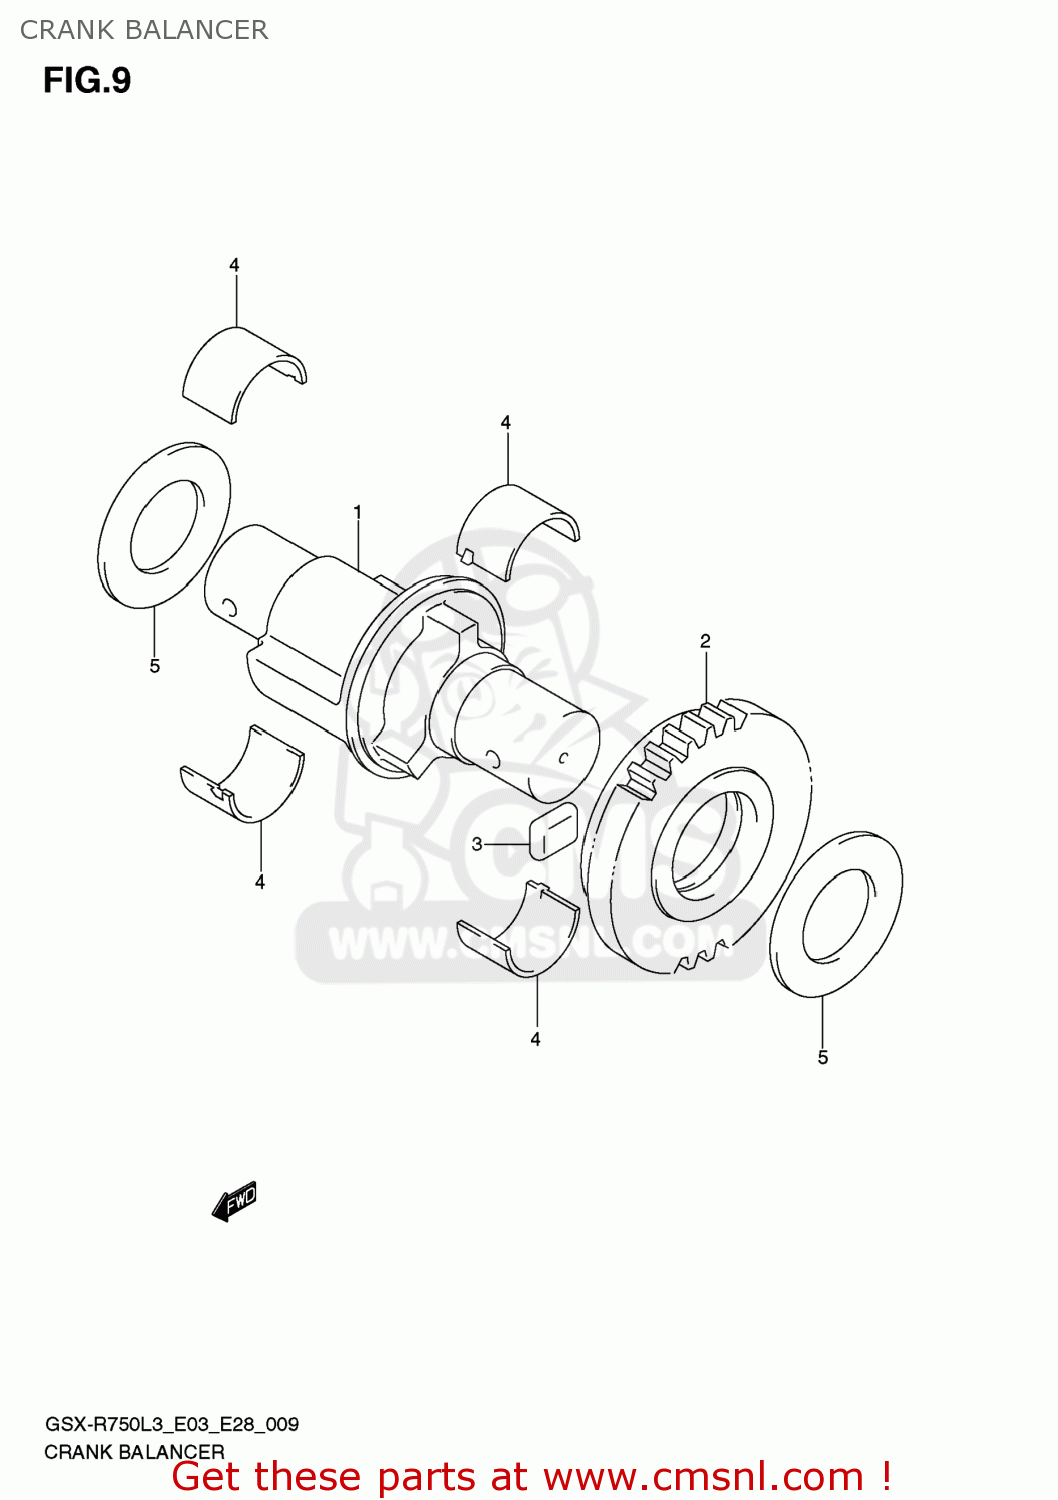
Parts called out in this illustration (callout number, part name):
1	BALANCER,CRANK
2	GEAR,CRANK BALANCER
3	DAMPER,CRANK BALANCER GEAR
4	BEARING,CRANK BALANCER
5	SHIM(23X40X2)
